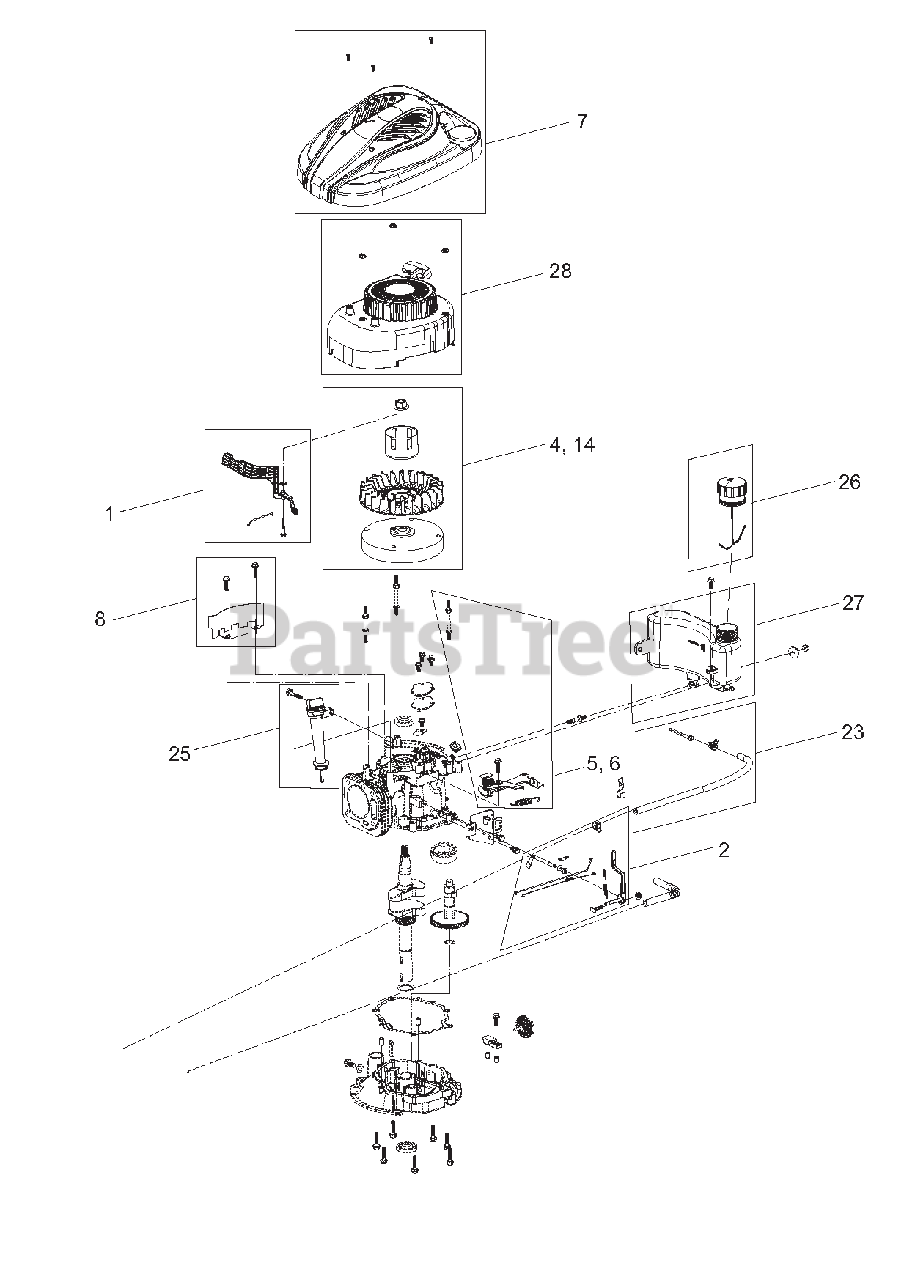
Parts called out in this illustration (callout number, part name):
1	KIT, AIR VANE CHOKE - SVC
2	KIT, GOVERNOR ARM - SVC
3	KIT, MUFFLER AND SHIELD - SVC
4	KIT, FLYWHEEL AND FAN - SVC
5	KIT, BRAKE ASM RECOIL - SVC
6	KIT, E-START BRAKE ASM - SVC
7	KIT, ARIENS STYLE - SVC
8	KIT, FLYWHEEL SHIELD - SVC
9	KIT, THERMAL CHOKE CONTROL-SVC
10	KIT, AIR CLEANER ASM - SVC
11	KIT, CARBURETOR COMPLETE - SVC
12	KIT, IGNITION COIL - SVC
13	KIT, SEAL AND GASKET - SVC
14	KIT, FLYWHEEL AND FAN - SVC
16	KIT, STARTER - SVC
17	KIT, WIRE HARNESS - SVC
18	KIT, VALVE COVER - SVC
19	LOCK, THROTTLE - SVC
20	STUD, INTAKE - SVC
21	ELEMENT, AIR CLEANER
22	FILTER, AIR - LONCIN 160CC
23	KIT, FUEL LINE W/FILTER - SVC
24	SPARK PLUG, LONCIN 160CC
25	DIPSTICK, OIL - SVC
26	CAP, FUEL - SVC
27	ASM, FUEL TANK W/HARDWARE
28	KIT, RECOIL - SVC
29	ENGINE,SERVICE,AC SERIES
29	ENGINE,SERVICE,AC SERIES,ELEC
